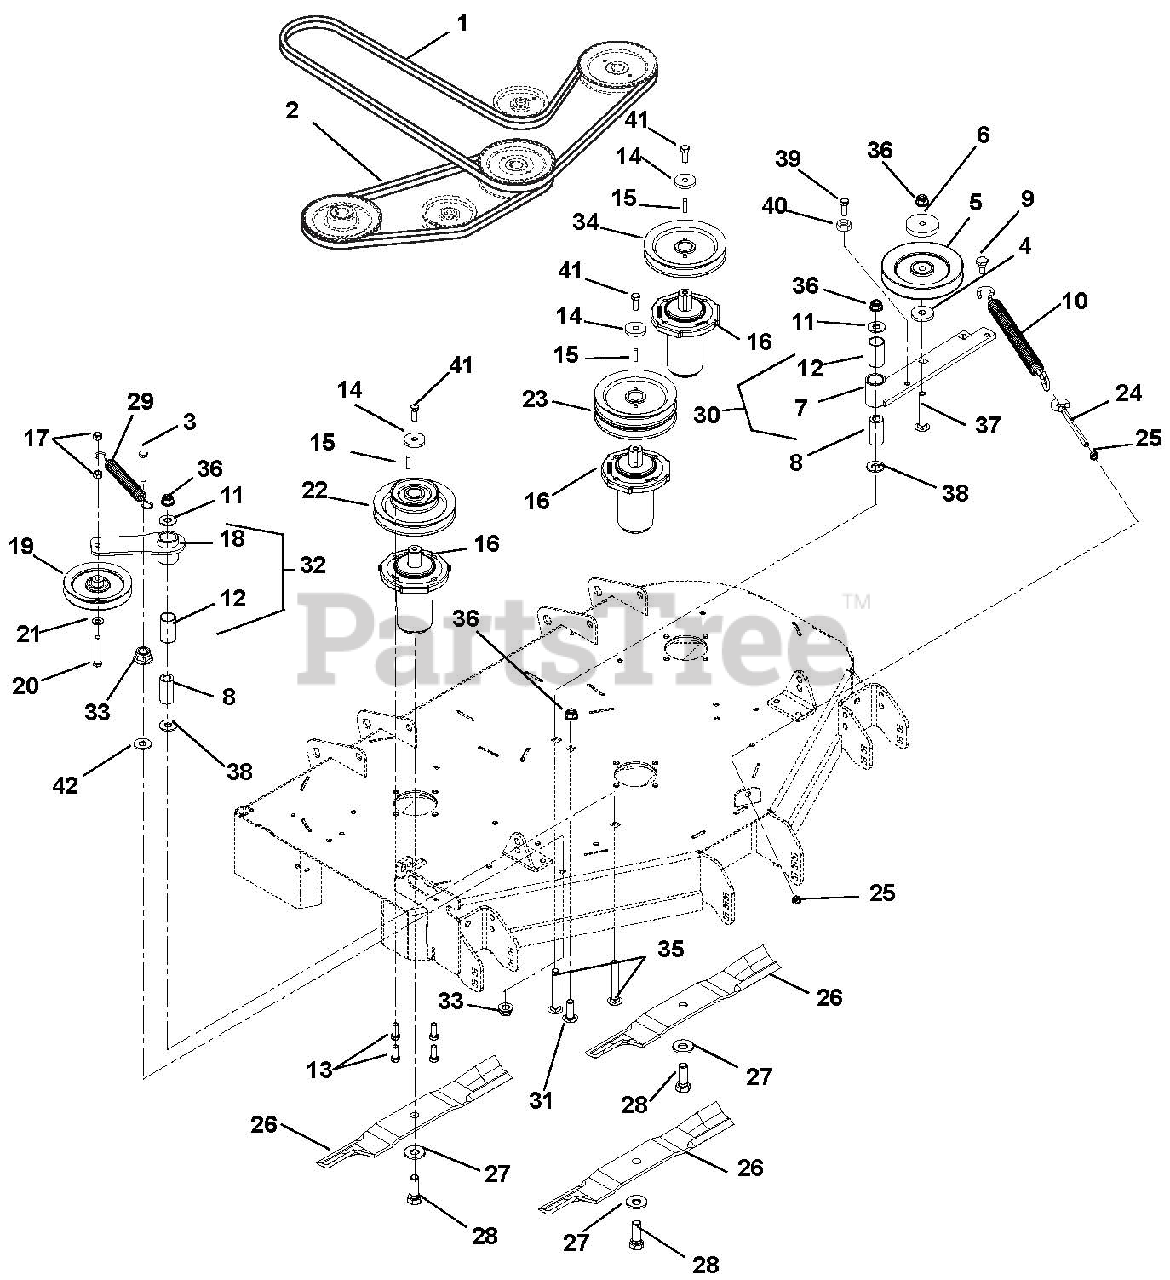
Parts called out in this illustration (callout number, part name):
1	Belt, BB 120.50 Wrapped Hex
2	Belt, B 51.18 Raw Cogged
3	Bolt, Hex .38-16 x 3.00 Grade 5
4	Bushing, Spacer .502 x .997 x .50
5	Sheave, .50" ID x 6.00" OD V-Idler
6	Cap, Idler Bearing Sealing
7	Idler Pivot Arm Weldment – Black
8	Bushing, Spacer .505/.500 x .999/.996 x 2.05/2.03
9	Bolt, Shoulder EP .38-16 x .30 Hex
10	Spring, Extension
11	Washer, Flat Steel .531 x 1.25 x .100
12	Bushing, 1.00 x 1.125 x 1.936
13	Bolt, Hex .38-16 x 1.00
14	Retainer, Sheave
15	Key, Square .25 x .25 x 1 RC 40-50
16	Spindle Assembly
17	Nut, Locking, Center .38-16
18	Idler, Pivot Arm
19	V-Idler, .38" ID x 5" OD
20	Bolt, Hex .38-16 x 2.25
21	Washer, Flat Steel .406 x .812 x .065
22	Pulley, Double 1" ID x 5.75" & 3.50" OD
23	Pulley, Double 1" ID x 5.75" OD
24	Bolt, .38-16 x 4.00 .62 Diameter Eye
25	Nut, Hex, Jam .375-16
26	Blade, 16.19" Mower
27	Washer, Bellville .63 x 1.625 x.14
28	Bolt, Hex .62-18 x 1.75 Grade 8
29	Spring, Extension (Deck Belt Idler)
30	Assembly, PTO Idler Pivot Arm
31	Bolt, Round Head Square Neck .50-13 x 1.5, Full Thread, Grade 5
32	Assembly, Idler Pivot Arm
33	Nut, Spin Lock-Flange .375-16
34	Sheave, Single 1.0" ID x 5.75" OD
35	Bolt, Round Head Square Neck .50-13 x 3.50
36	Nut .50-13 Nyloc Flange
37	Bolt, Round Head Square Neck .50-13 x 3.00 Grade 5
38	Washer, Flat .640 x 1.75 x .250
39	Bolt, Hex .38-16 x 2.75 Grade 5
40	Nut, Hex .38-16
41	Bolt, Hex .38-16 x 2.75 Grade 8
42	Washer, Flat Steel .406 x 1.375 x .135 YZ
